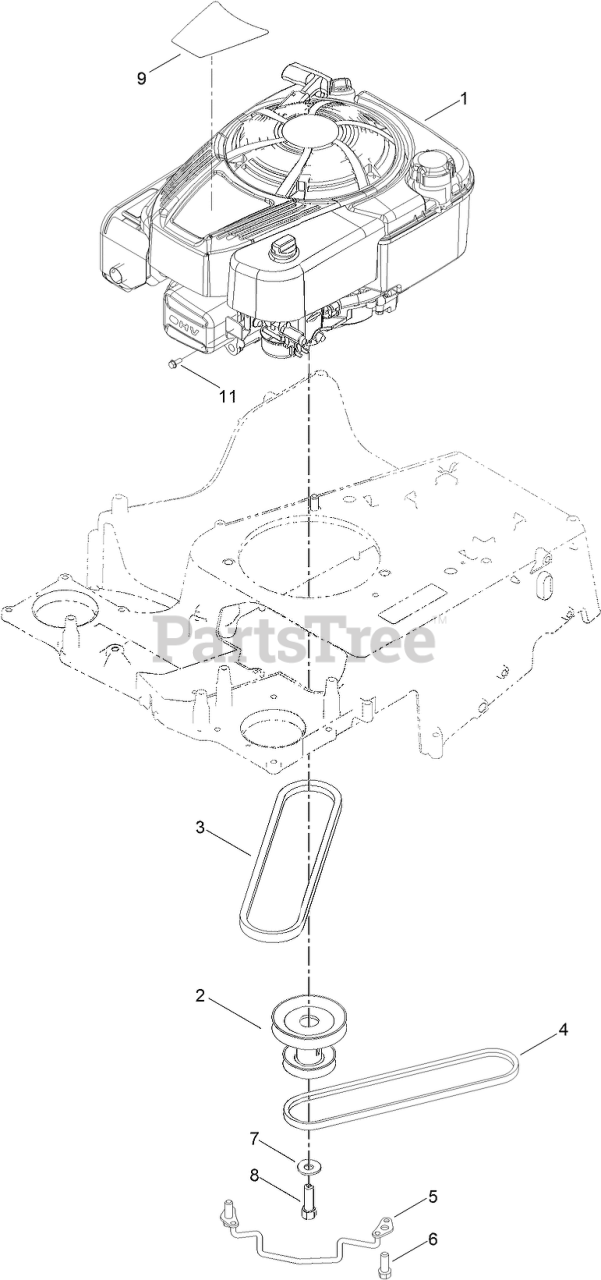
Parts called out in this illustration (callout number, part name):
2	PULLEY-ENGINE
3	V-BELT
4	V-BELT, TRACTION
5	GUIDE-BELT
6	SCREW-TAPTITE
7	WASHER-BELLEVILLE
8	SCREW-HH
9	DECAL-SHROUD
11	SCREW-TAPTITE
